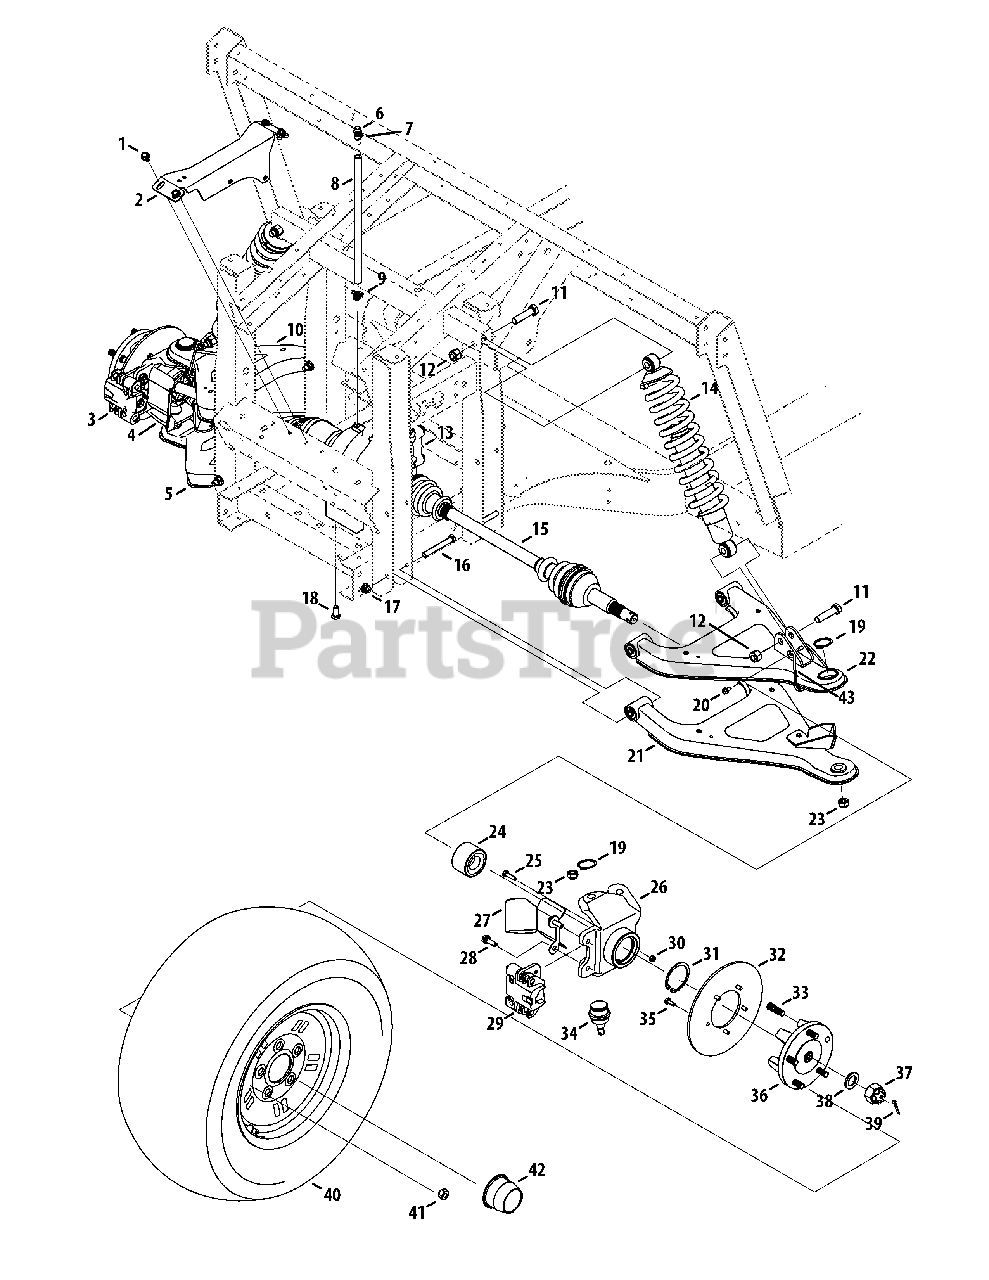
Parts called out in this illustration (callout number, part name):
1	Screw, tt, 5/16-18 x 0.500
2	Front Mount, differential, 4x4
3	Brake, hydraulic, caliper, frt, RH
4	Housing, knuckle, r/frt, mach
5	Control Assembly, r/frt, lower
6	Vent,3/8 Dia
7	Clamp, hose, .490 Dia.
8	Hose, Fuel Line
9	Clamp, Hose, Adj.
10	Arm Assembly, r/frt, upper
11	Screw, 1/2-13 x 2.00, gr5, std
12	Nut, Hex Lock, 1/2-13, Nylon
13	Differential Assembly, cfd, 4x4
14	Shabs, 5.0 Stroke, front
15	Axle Assembly, cv Joint, 4x4
16	Screw, 3/8-16 x 3.00, gr8, std
17	Nut, Flange Lock, 3/8-16, Nylon
18	Screw, 3/8-16, .75, gr5, std
19	Ring, retainer, 34 x 1.6
20	Screw, tt, 1/4-20 x .500
21	Control Assembly, l/ftr, lower
22	Control Assembly, l/frt, upper
23	Nut, Nylock, m12 x 1.25
24	Bearing, dble Row, 60x30x37
25	Screw, 1/4-20 x 1.00, gr5, spec
26	Housing, knuckle, l/frt, mach
27	Bracket, Steering Shield, LH
28	Screw, m8-1.25, 25.00
29	Brake, hydraulic, caliper, frt, LH
30	Nut, Hex, 1/4-20, gr5
31	Ring, retainer, dho-60
32	Disc, brake, 8.00x.188
33	Stud, rib Neck, 7/16-14 x 1.6
34	Ball Joint, 14d-6201
35	Screw, 1/4-20 x .625, gr5, lock
36	Hub, wheel
37	Nut, slotted, 22x1.5
38	Washer, flat, .88 x 1.38 x .125, ht
39	Pin, cotter, 5/32, 1.25
40	Wheel Assembly, rh, 26 x 9-12
40	Wheel Assembly, lh, 26 x 9-12
41	Nut, lug, 7/16-14
42	Cap, Wheel
43	Wire, Brake Line
